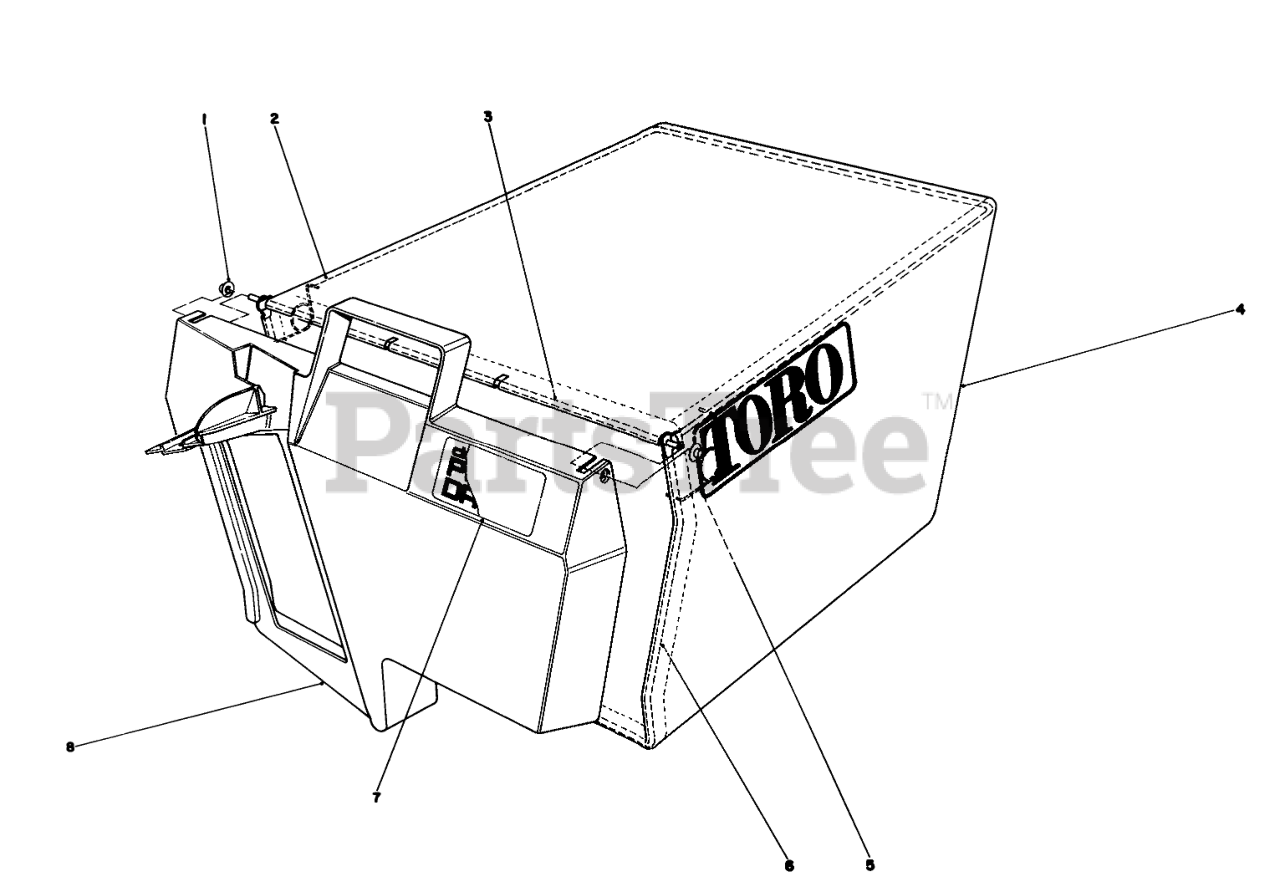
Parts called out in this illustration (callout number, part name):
1	NUT-PUSH
2	FRAME-BAG, UPPER
3	HINGE-DOOR, BAG
4	BAG-GRASS
5	SPRING
6	FRAME-BAG
7	BAG DOOR DECAL
8	DOOR-BAG
